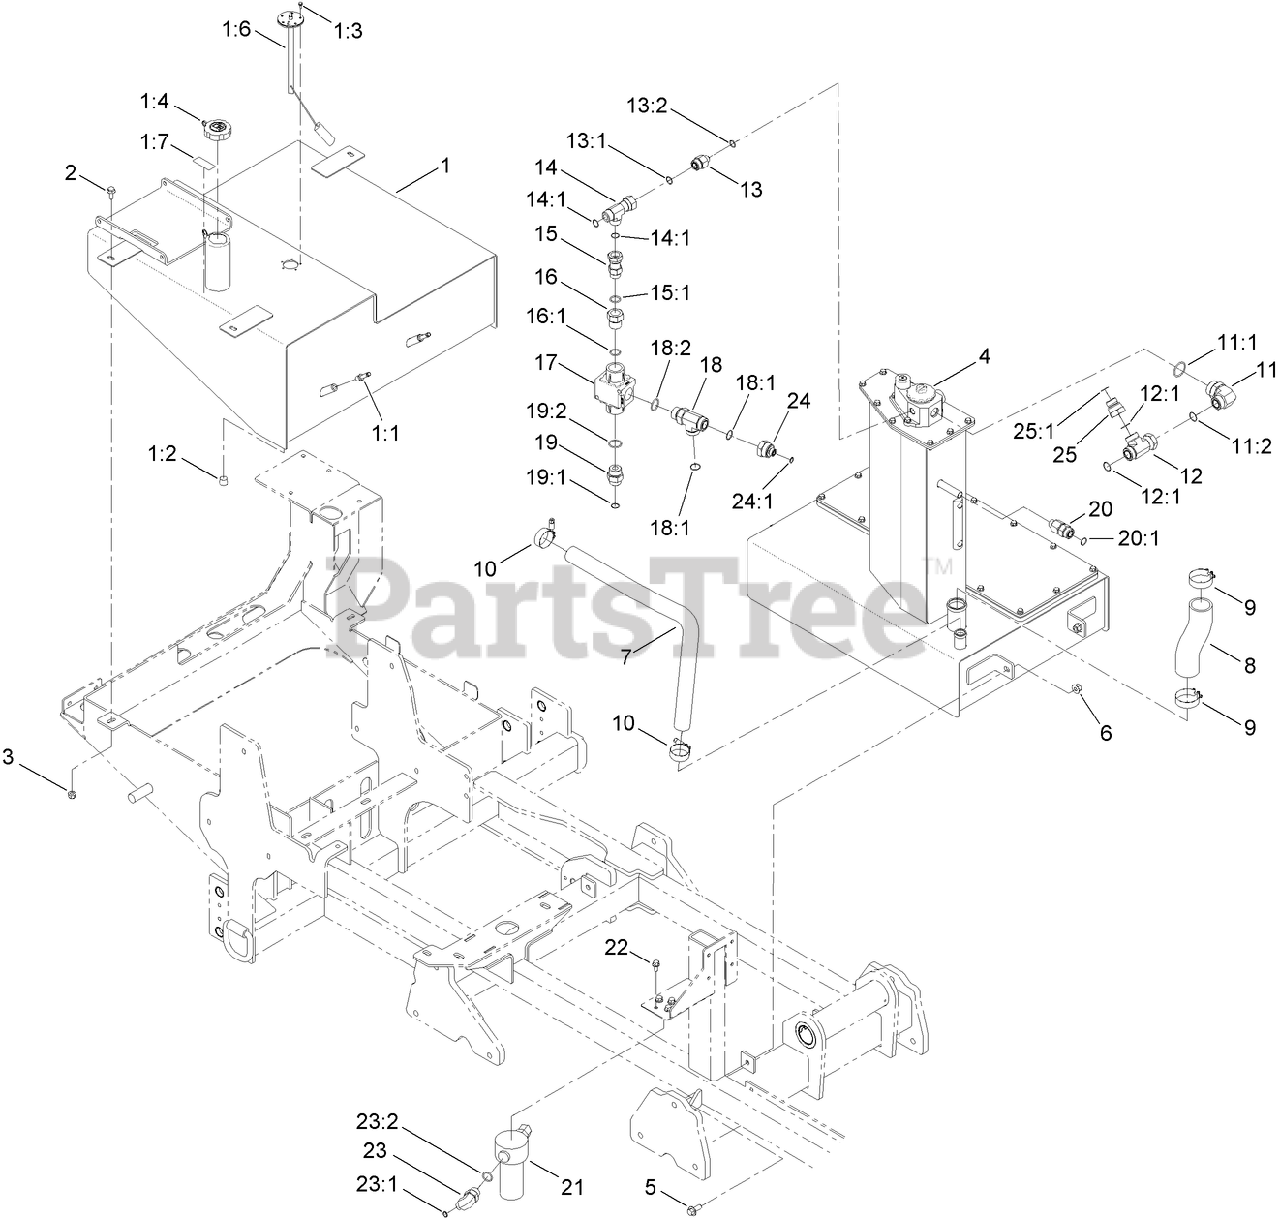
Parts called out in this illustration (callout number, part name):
1	FUEL TANK ASM
1:1	STEM-STRAIGHT, BEAD
1:2	PLUG-PIPE, HEX SOCKET
1:3	SCREW-TAPTITE
1:4	CAP-DIESEL FUEL W/ LOCK
1:6	SENDER-FUEL
1:7	DECAL-LOW SULFUR
2	SCREW-HHF
3	NUT-LOCK, NI
4	HYDRAULIC TANK ASM
5	SCREW-HHF
6	NUT-LOCK, HHF
9	CLAMP, T-BOLT
10	CLAMP-HOSE (T-BOLT)
11	FITTING-ELBOW 90
11:1	O-RING
11:2	O-RING
12	FITTING-TEE
12:1	O-RING
13	FITTING-STR
13:1	O-RING
13:2	O-RING
14	FITTING-TEE
14:1	O-RING
15	Fitting-HYD, Swivel
15:1	O-RING
16	FITTING-STRAIGHT
16:1	O-RING
17	VALVE-THERMOSTAT
18	FITTING-TEE
18:1	O-RING
18:2	O-RING
19	FITTING-STR
19:1	O-RING
19:2	O-RING
20	FITTING-STRAIGHT
20:1	O-RING
21	FILTER-HYD, 350PSI (6 MICRON)
22	SCREW-HHF
23	FITTING-HYD, 90 DEG
23:1	O-RING
23:2	O-RING
24	FITTING-REDUCER
24:1	O-RING
25	FITTING-REDUCER
25:1	O-RING
